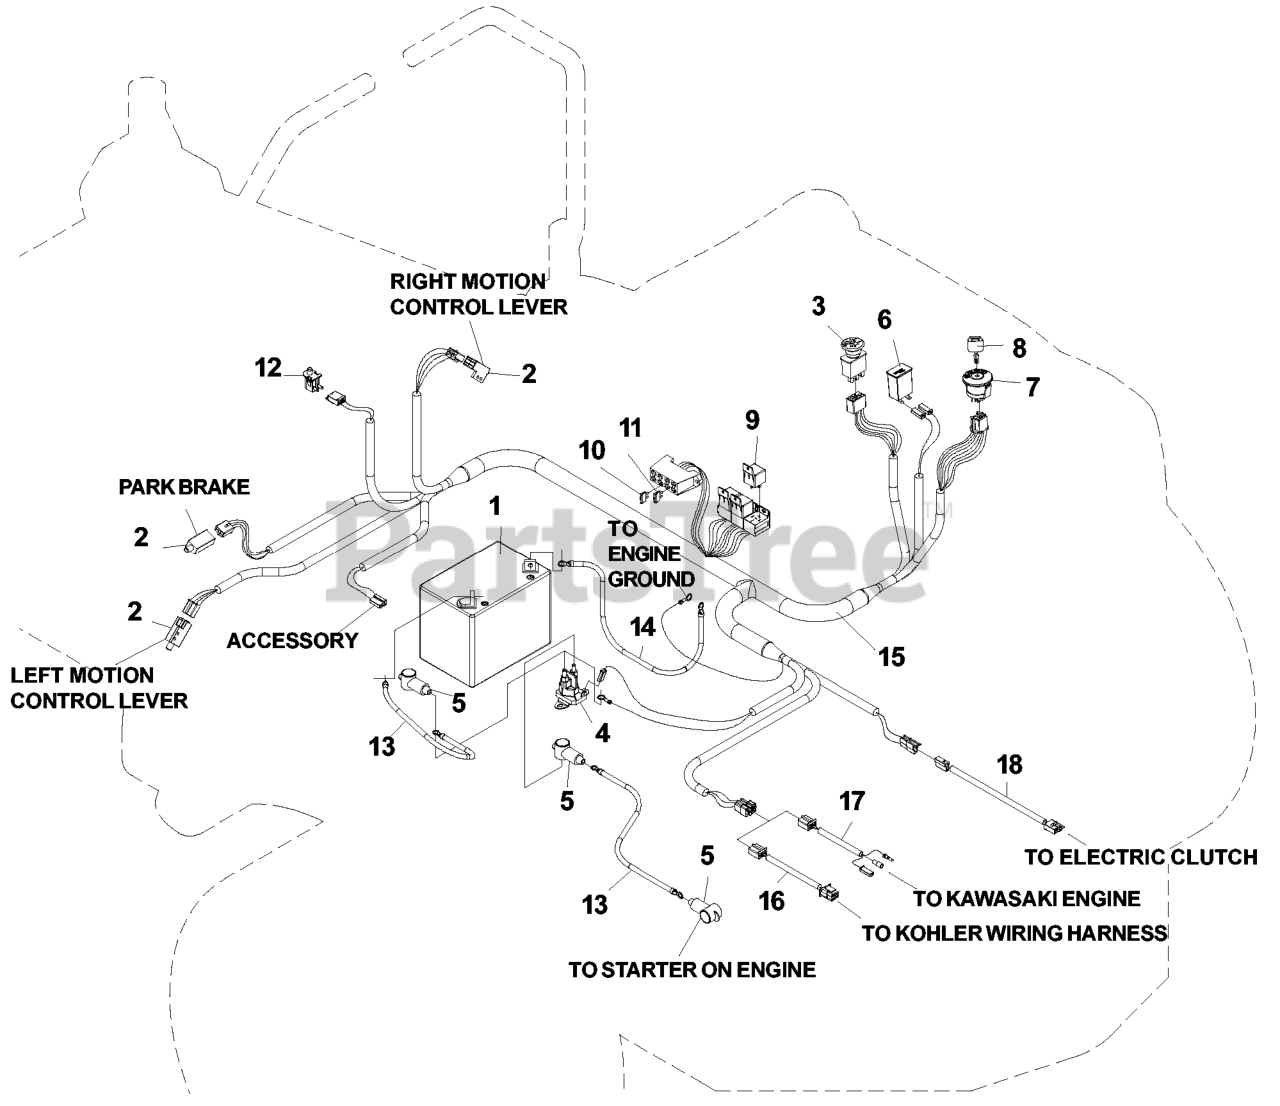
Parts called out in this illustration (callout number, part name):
1	BATTERY, 12 V 330 AMP
2	SWITCH, INTERLOCK
3	RP.SWITCH, BLADE
6	HOUR METER
7	RP IGNITION SWITCH
8	KEY
10	FUSE, 20 AMP 32 VOLT ATO
11	FUSE, 7.5 AMP 32 VOLT ATO
12	SEAT SWITCH
13	BATTERY CABLE-POS
14	BATTERY CABLE-NEG
15	WIRING HARNESS
16	KOHLER PIGTAIL-CV490S
17	KAW PIGTAIL
18	CLUTCH HARNESS
